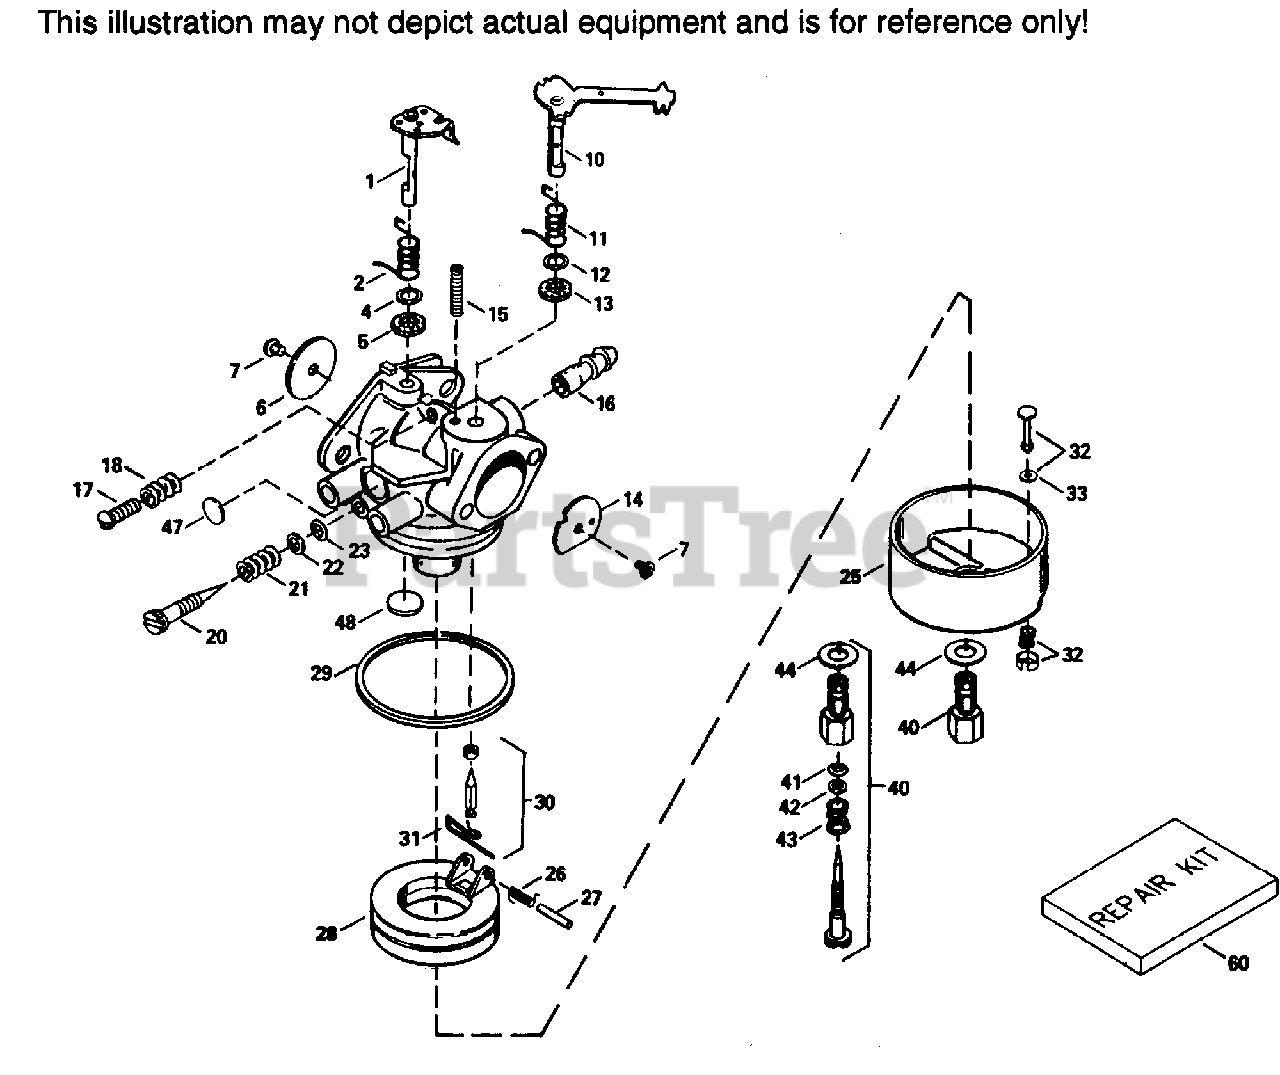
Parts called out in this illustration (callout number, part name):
1	Throttle Shaft & Lever Assembly
2	Throttle Return Spring
6	Throttle Shutter
7	Shutter Screw
10	Choke Shaft & Lever Assembly
14	Choke Shutter
15	Choke Positioning Spring
16	Fuel Fitting
17	Throttle Crack Screw/Idle Speed Screw
18	Tension Spring
20	* Idle Mixture Screw
21	Tension Spring
22	Idle Mixture Screw Washer
23	* Idle Mixture Screw "O" Ring
25	Float Bowl
27	* Float Shaft
28	Float
29	* Float Bowl "O" Ring
30	* Inlet Needle, Seat & Clip (Incl. 31)
31	Spring Clip
40	* Main Adj. Screw Ass'y. Incl. 41 thru4 4
41	* High Speed Mixture Screw "O" Ring
42	High Speed Mixture Screw Washer
43	High Speed Mixture Screw Tension Spri ng
44	* Bowl Nut Washer
47	* Welch Plug, Idle Mixture Well
48	* Welch Plug, Atmospheric Vent
60	Repair Kit Incl. items marked PK inn otes
